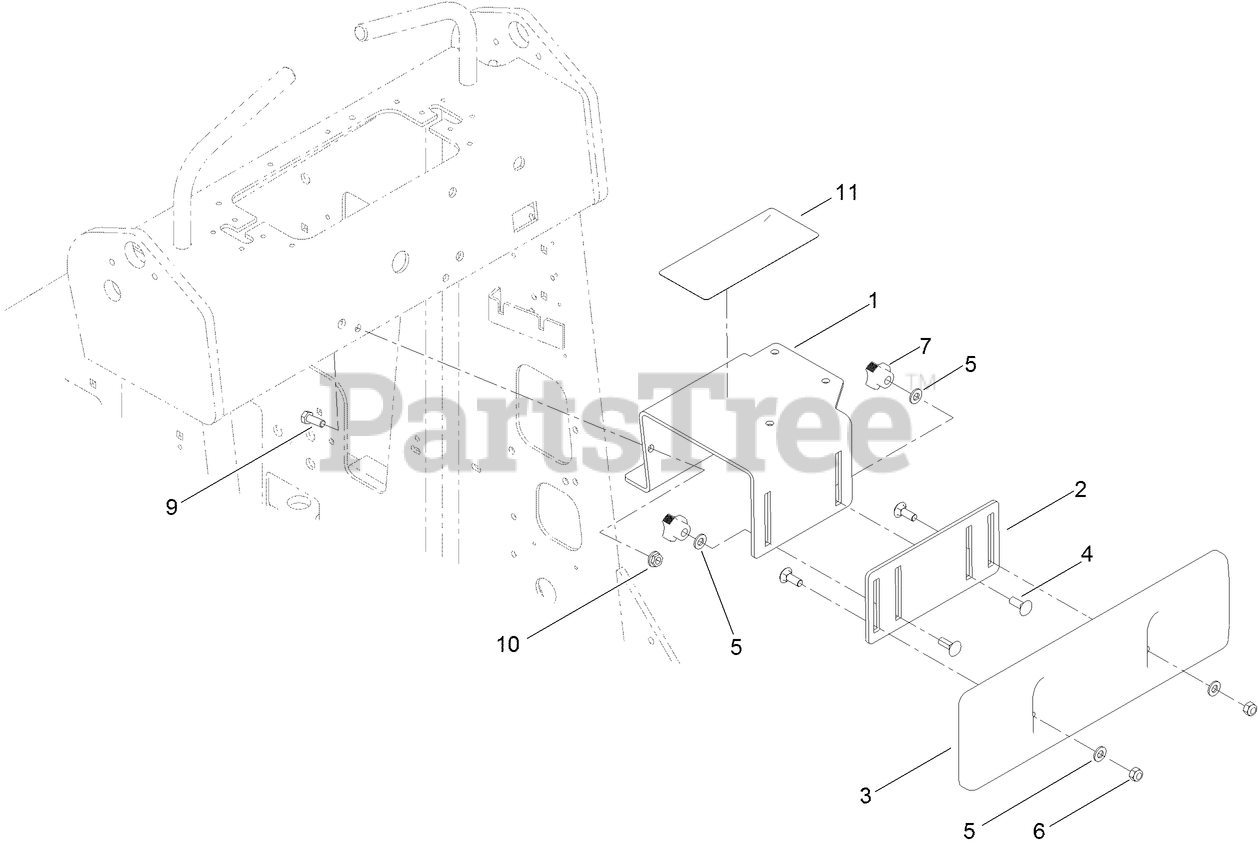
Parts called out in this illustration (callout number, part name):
1	BRACKET-THIGH SUPPORT
2	PLATE-ADJUSTING
3	SUPPORT-THIGH
4	SCREW-CARR
5	WASHER-FLAT
6	NUT-LOCK, NI
7	KNOB-ADJUSTMENT
9	SCREW-HH
10	NUT-HF
11	DECAL-SERVICE
